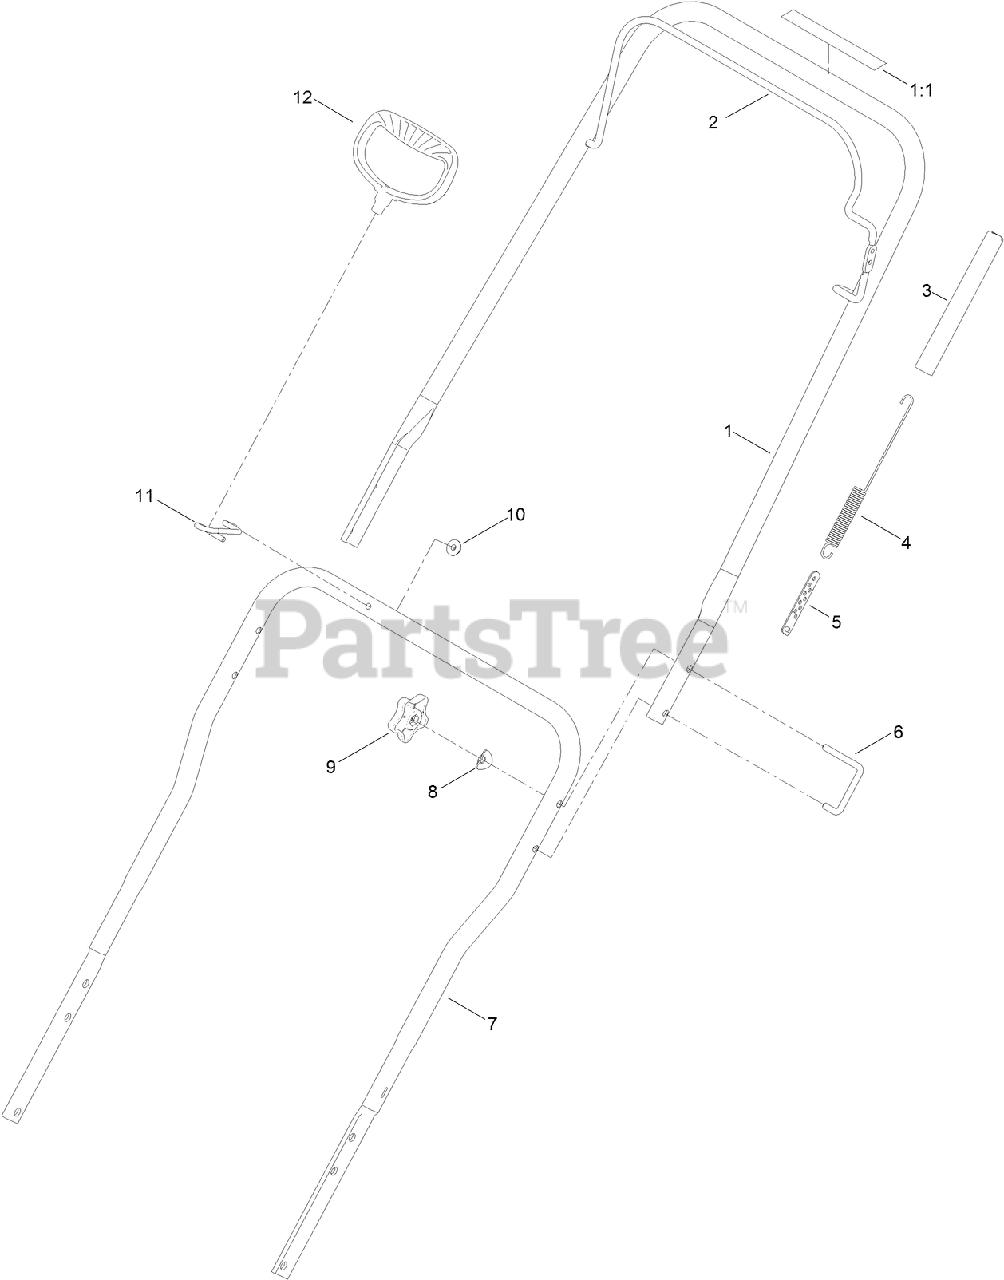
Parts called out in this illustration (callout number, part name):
1	UPPER HANDLE ASM
1:1	DECAL-DRIVE, ROTOR
2	BAIL-CLUTCH
3	COVER-SPRING
4	SPRING-EXTENSION, CLUTCH
7	HANDLE-LOWER
8	WASHER
9	KNOB-HANDLE
10	NUT-HF
11	GUIDE-ROPE
12	HANDLE-RECOIL
